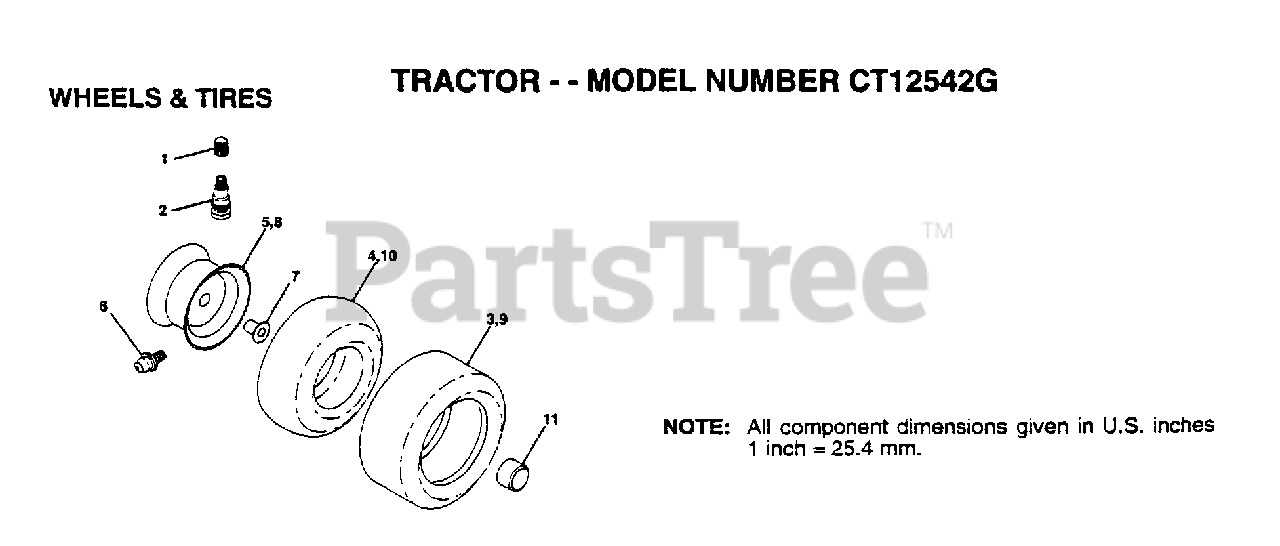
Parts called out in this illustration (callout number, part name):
1	VALVE CAP
2	VALVE STEM LT
4	TUBE.5.3/4.5/6
5	"RIM.ASM.6""FRONT"
6	FITTING LT
7	"FLANGE, BEARING"
8	"RIM.ASM.8""REAR"
10	TUBE.18X9.5-8
11	HUB CAP
